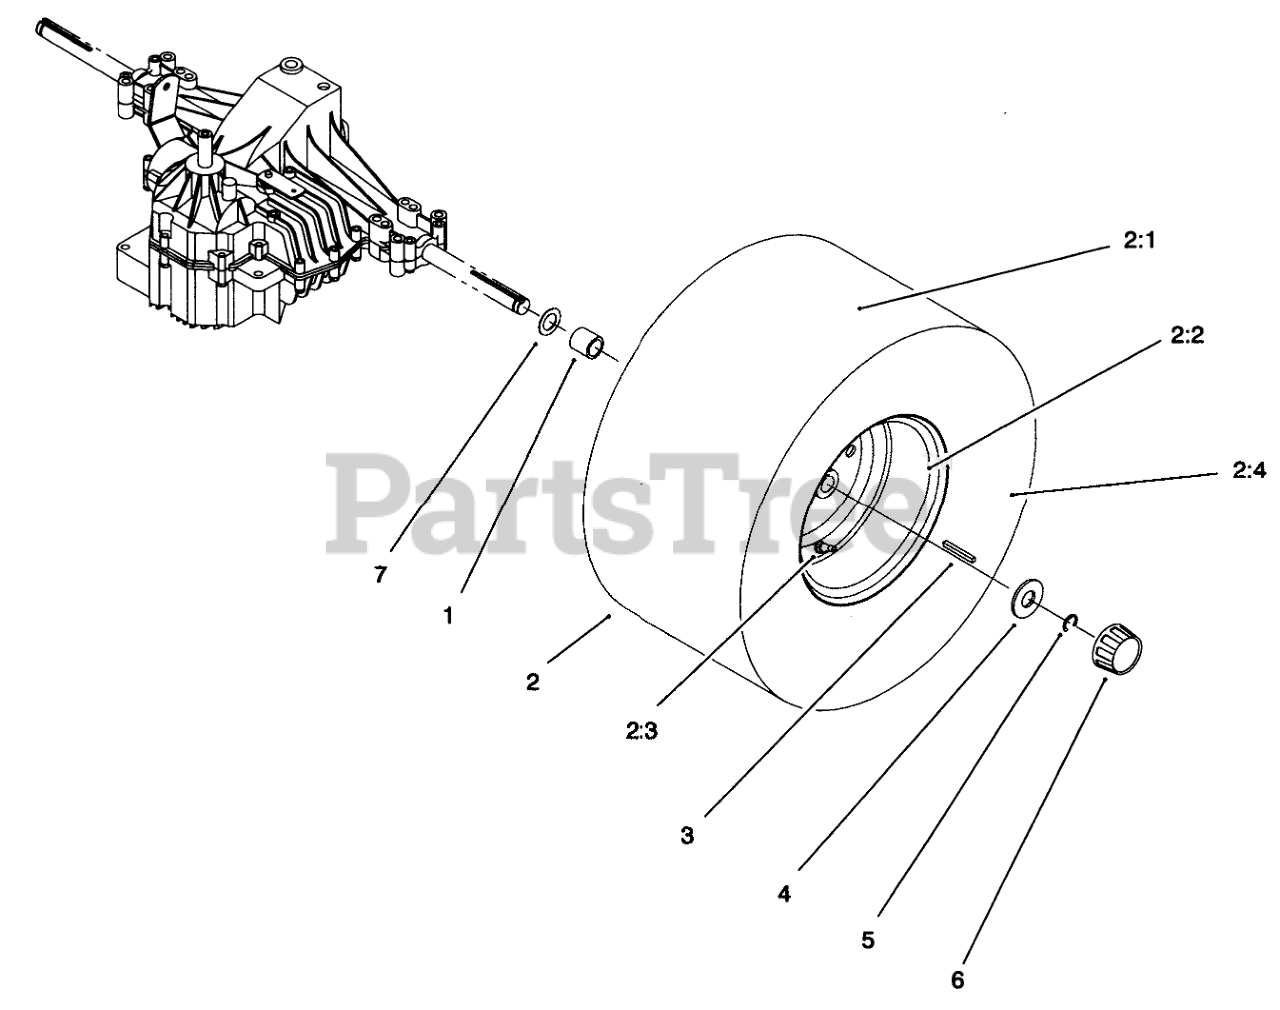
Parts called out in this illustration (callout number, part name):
1	SPACER
2:1	TIRE 20 INCH
2:3	STEM-VALVE
2:4	TUBE-INNER
3	KEY-SQUARE
4	WASHER-PLAIN
5	E-RING
6	CAP-HUB
7	WASHER-THRUST
